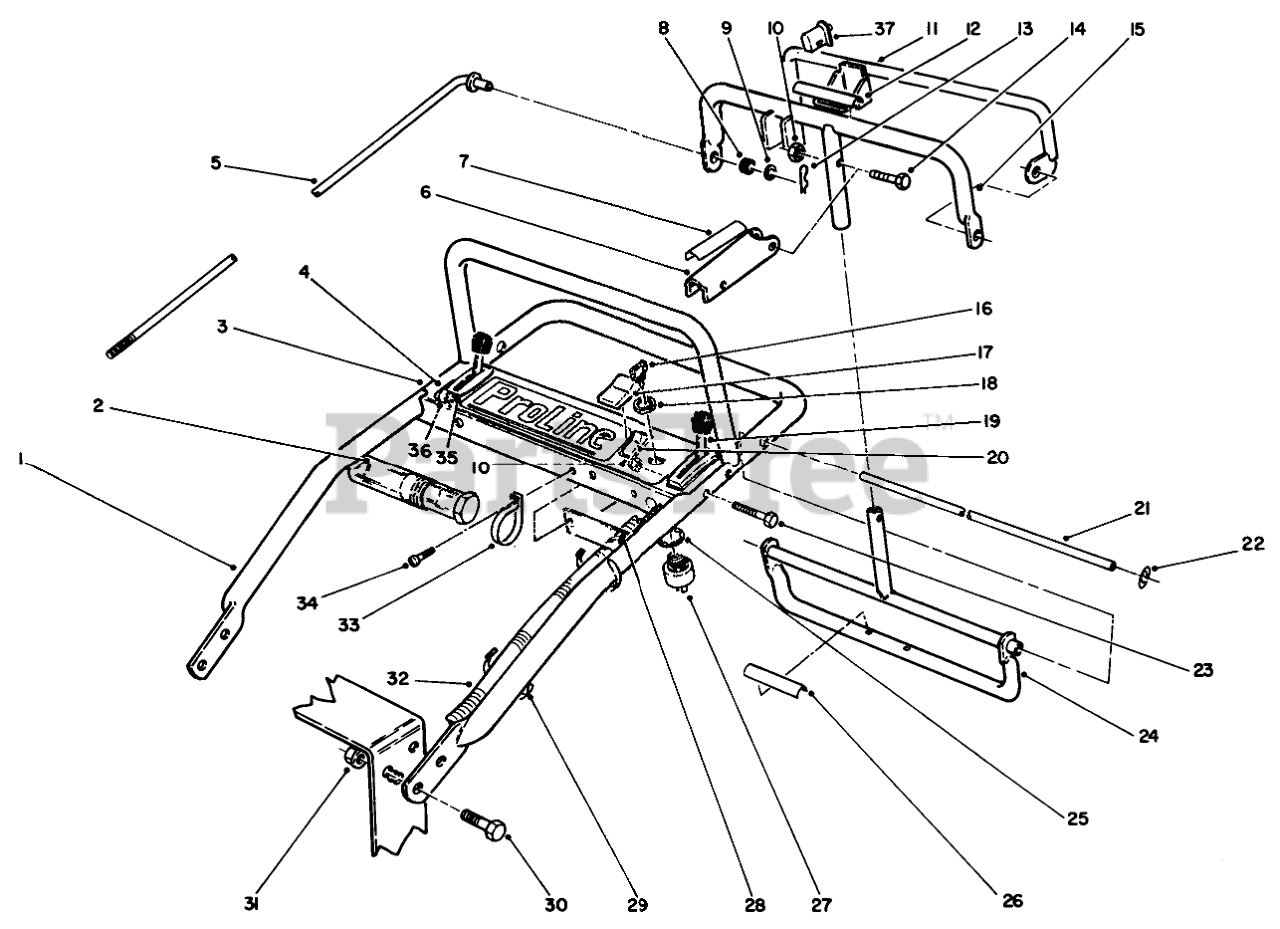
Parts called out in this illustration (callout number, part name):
1	Handle-Upper
2	TUBE-MANUAL
3	Panel-Control
4	DECAL-CNTRL PANEL-30175
5	ROD-CONTROL
6	Lever-Parking Brake
7	DECAL-LEVER, PARKING
8	GROMMET-RUBBER
9	WASHER-FLAT
10	NUT-LOCK, NI
11	SWITCH-BAIL
12	DECAL
13	PIN-COTTER
14	SCREW-SHH
15	Bar
16	KEY-IGNITION
17	BOOT-SWITCH
18	NUT-HH
19	THROTTLE CONTROL
20	Switch-Clutch (Incl. Ref. #17)
21	PIVOT ROD
22	NUT-PUSH-ON, CIRCULAR
23	SCREW-SHH
24	Control Pivot
25	WASHER-TOOTH, INTERNAL
26	DECAL
27	Switch-Ignition (Incl. Ref. #16, 18, & 25)
28	Panel-Bottom
29	TIE-CABLE
30	SCREW-HHF
31	NUT-HF
32	Wire HARness
33	CLAMP-R
34	SCREW-HWHTF
35	CHOKE CONTROL
36	SPACER
37	Bail
